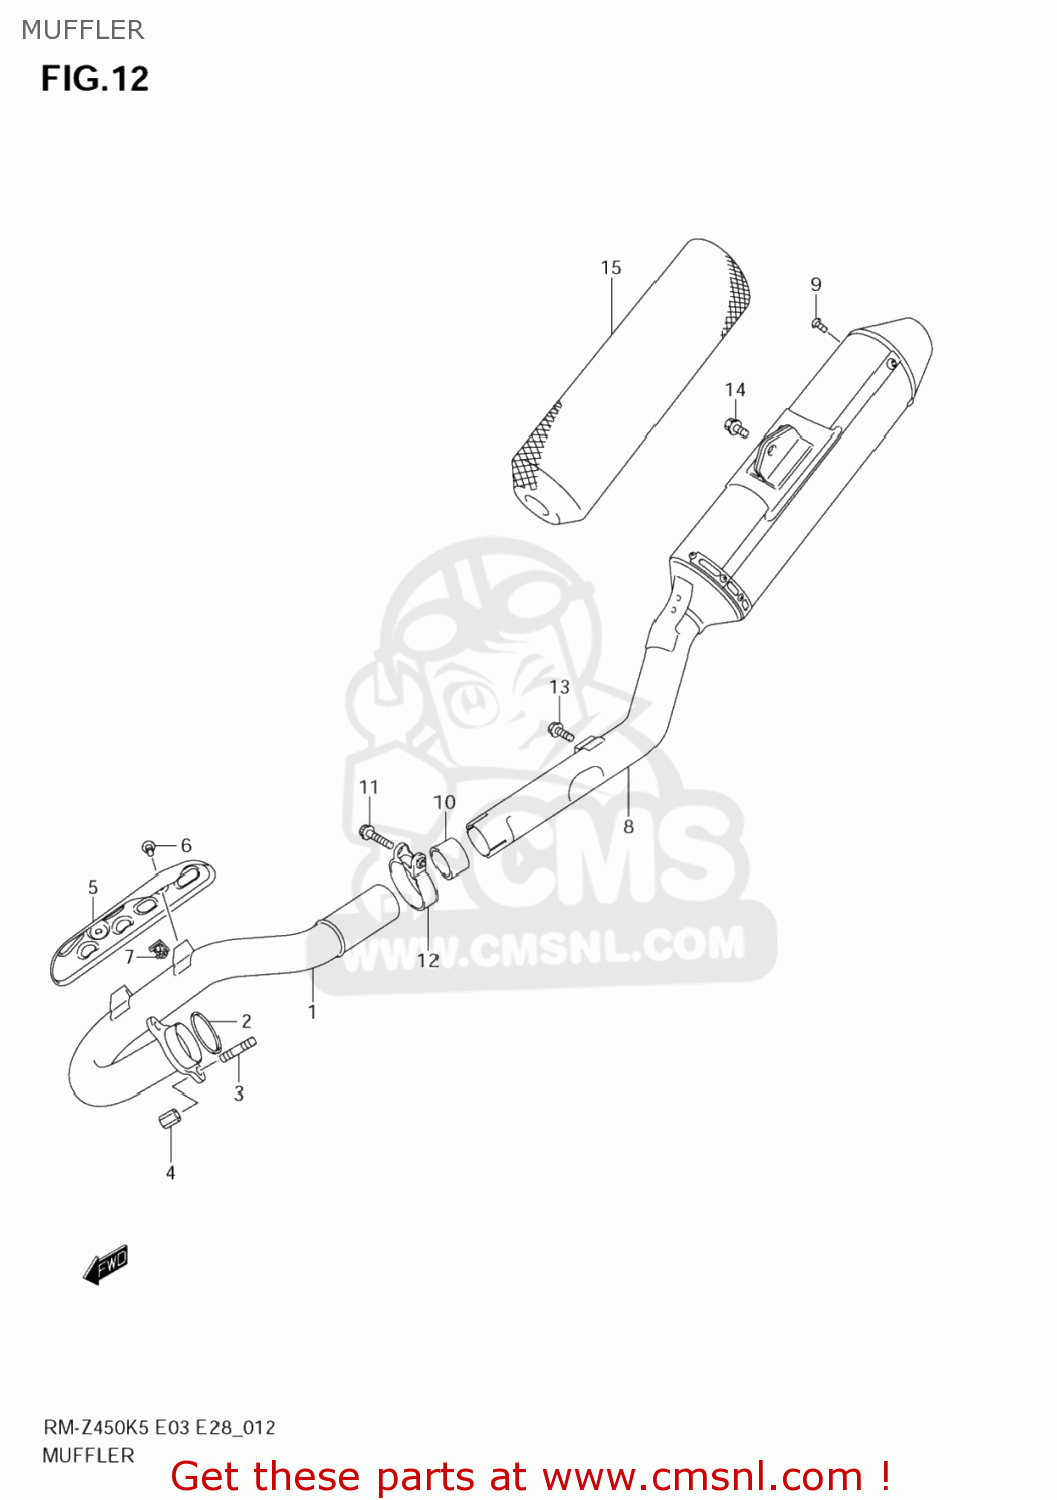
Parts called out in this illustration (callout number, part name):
1	PIPE,EXHAUST
2	GASKET,EXHAUST PIPE (NAS)
3	BOLT
4	NUT
5	COVER,EXHAUST
6	SCREW(6X10)
7	NUT
8	BODY,MUFFLER
9	SCREW(5X13)
10	CONNECTOR,MUFFLER JOINT
11	BOLT
12	CLAMP,CONNECTOR
13	BOLT(8X16)
14	BOLT
15	SILENCER,MUFFLER
